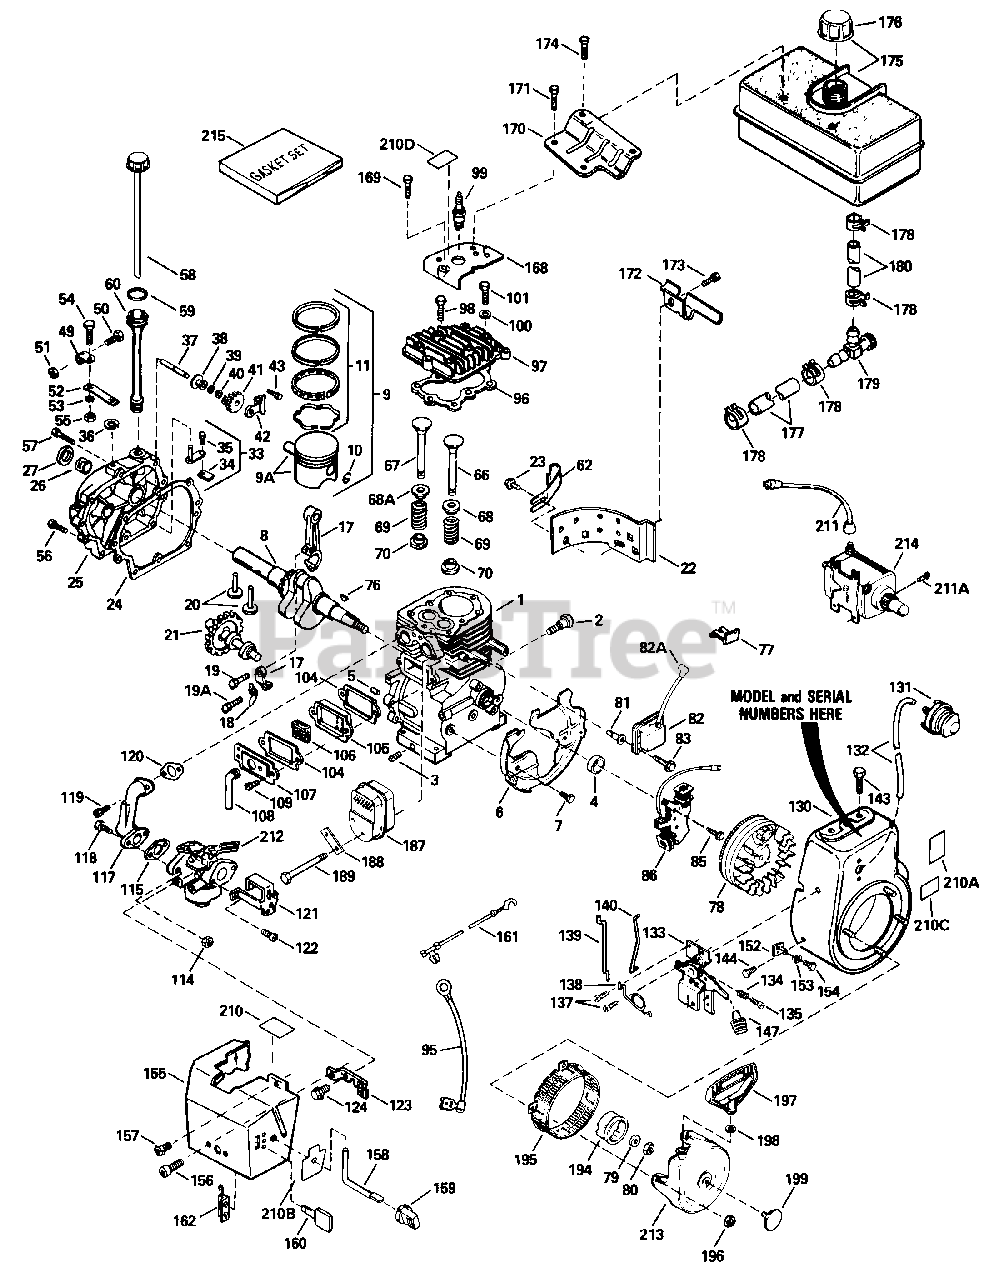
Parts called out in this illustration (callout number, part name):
1	Cylinder
2	Screw, Hex Hd. Shoulder, 1/4-20 X 1/2
3	Plug, Pipe
4	Seal, Oil
5	Pin, Dowel
6	Baffle, Blower Housing
7	Screw, Hex Washer Hd. Durlok, 1/4-20 x 5/8
8	Crankshaft
9	Piston, Pin & Ring Ass'y.
9A	Piston & Pin Ass'y. (Std.)
10	Ring, Piston Pin Retaining
11	Ring Set, Piston (Std.)
11	Ring Set, Piston (.010 Oversize)
11	Ring Set, Piston (.020 Oversize)
17	Rod Ass'y., Connecting
18	Dipper, Oil
19	Bolt, Connecting Rod
19A	Bolt, Connecting Rod
20	Lifter, Valve
21	Camshaft (Mechanical Compression Release)
22	Extension, Blower Housing
23	Screw, Hex Hd. Sems, 10-24 x 1/2
24	Gasket, Cylinder Cover
25	Cover Ass'y., Cylinder
26	Bushing, Crankshaft
27	Seal, Oil
33	Rod Ass'y., Governor
34	Yoke, Governor
35	Screw, Fil. Hd. Sems, 6-40 x 5/16
36	Ring, Retaining
37	Shaft, Governor
38	Spool, Governor
39	Washer, Flat
40	Ring, Retaining
41	Gear, Governor
42	Bracket, Governor Gear
43	Screw, Hex Washer Hd. Thread Forming, 10-24 x 1 1/2
49	Clamp, Governor Lever
50	Screw, Hex Washer Hd., 10-32 x 3/4
51	Lock Nut, Hex "Keps," 10-32
52	Lever, Governor
53	Washer, E.T. Lock
54	Screw, Hex Washer Hd., 8-32 x 5/16
55	Lock Nut, Hex "Keps," 8-32
56	Screw, Hex Washer Hd. Powerlok, 1/4-20 x 1-11/16
57	Screw, Hex Washer Hd. Powerlok, 1/4-20 x 1-3/16
58	Dipstick, Oil
60	Tube, Oil Fill
62	Clip, Fill Tube
66	Valve, Exhaust (Std.)
66	Valve, Exhaust (1/32" Oversize)
67	Valve, Intake (Std.)
67	Valve, Intake (1/32" Oversize)
68	Cap, Upper Valve Spring
68A	Seal Ass'y., Intake Valve
69	Spring, Valve
70	Cap, Lower Valve Spring
76	Key, Flywheel
77	Clip, Spring
78	Flywheel (w/ring gear)
79	Washer, Lock
80	Nut, Flywheel
81	Stud, Solid State Mounting
82	Solid State Ass'y.
82A	Cover, Spark Plug
83	Screw, Hex Hd. Sems, 10-24 x 1
85	Screw, Hex Hd. Sems, 1/4-20 x 3/4
86	Coil Ass'y., Alternator (18 Watt)
95	Wire, Ground
96	Gasket, Cylinder Head
97	Head, Cylinder
98	Screw, Hex Flange Hd. 5/16-18 x 1-1/2
99	Spark Plug (Champion J-8C or Equivalent)
100	Washer, Flat
101	Screw, Special Hex. Hd. Tapped, 5/16-18 x 1-3/4
104	Gasket, Breather
105	Body, Breather
106	Element, Breather
107	Cover, Breather
108	Tube, Breather
109	Screw, Hex Hd. Sems, 10-24 x 1/2
114	Nut & Lock Washer, 1/4-28
115	Gasket, Carburetor
117	Pipe, Intake
118	Screw, Fil. Hd. Sems, 1/4-28 x 1
119	Screw, Torx Fil. Hd. Sems, 5/16-18 x 1-1/8
120	Gasket, Intake Pipe
121	Bracket, Choke
122	Screw, Fil. Hd. Sems, 10-32 x 1/2
123	Bracket, Carburetor Cover Mounting
124	Screw, Hex Washer Hd. Sems, Taptite, 8-36 x 5/8
130	Housing, Blower
131	Primer Ass'y.
132	Line, Primer
133	Bracket Ass'y., Control
134	Spring, Compression
135	Screw, Fil. Hd., 5-40 x 7/16
137	Screw, Hex Washer Hd. Thread Cutting, 10-32 x 1/2
138	Spring, Speed Control
139	Link, Governor
140	Link, Governor-to-throttle
143	Screw, Hex Hd. Spinlock Thread Forming, 5/16-18 x 3/4
144	Screw, Phil. Hex Hd. Sems, 5/16-24 x 21/32
147	Knob, Control
152	Bracket, Grommet Mounting
153	Grommet, Plastic
154	Screw, Pan Hd. Taptite, 8-32 x 3/8
155	Cover, Carburetor
156	Screw, Hex Washer Hd. Sems, 10-32 x 3/8
157	Screw, Hex Washer Hd. Self-Drilling, 10-32 x 1/2
158	Rod, Choke
159	Knob, Choke
160	Ignition, Key
161	Wire, Ground
162	Terminal Ass'y.
168	Cover, Cylinder Head
169	Screw, Hex Washer Hd. Taptite, 1/4-20 x 5/8
170	Plate, Fuel Tank Mounting
171	Screw, Hex Hd., 5/16-18 x 5/8
172	Bracket, Fuel Tank
173	Screw, Hex Washer Hd. Durlok, 1/4-20 x 5/8
174	Screw, Hex Washer Hd. Thread Cutting, 1/4-15 x 7/8
175	Tank, Fuel
176	Cap, Fuel Tank
177	Line, Fuel
178	Clamp, Fuel Line
179	Valve, Fuel Shut-Off
180	Line, Fuel
188	Plate, Lock
189	Screw, Flanged Hex Hd., 5/16-18 x 4-3/16
194	Hub, Starter
195	Screen, Starter
196	Nut & Lock Washer, 1/4-28
197	Starter Handle, Mitten Grip
198	Washer, Flat
199	Plug, Starter
210	Decal, Instruction
210A	Decal, Name
210B	Decal, Choke
210C	Decal, Primer
210D	Decal, Warning (Bilingual)
211	Cord, Extension
211A	Screw, Hex Washer Hd. Sems, 1/4-20 x 1/2
212	Carburetor
213	Starter, Rewind
214	Motor Kit, Electric Starter (120 Volt)--See Electric Starter Motor
215	Gasket Set
